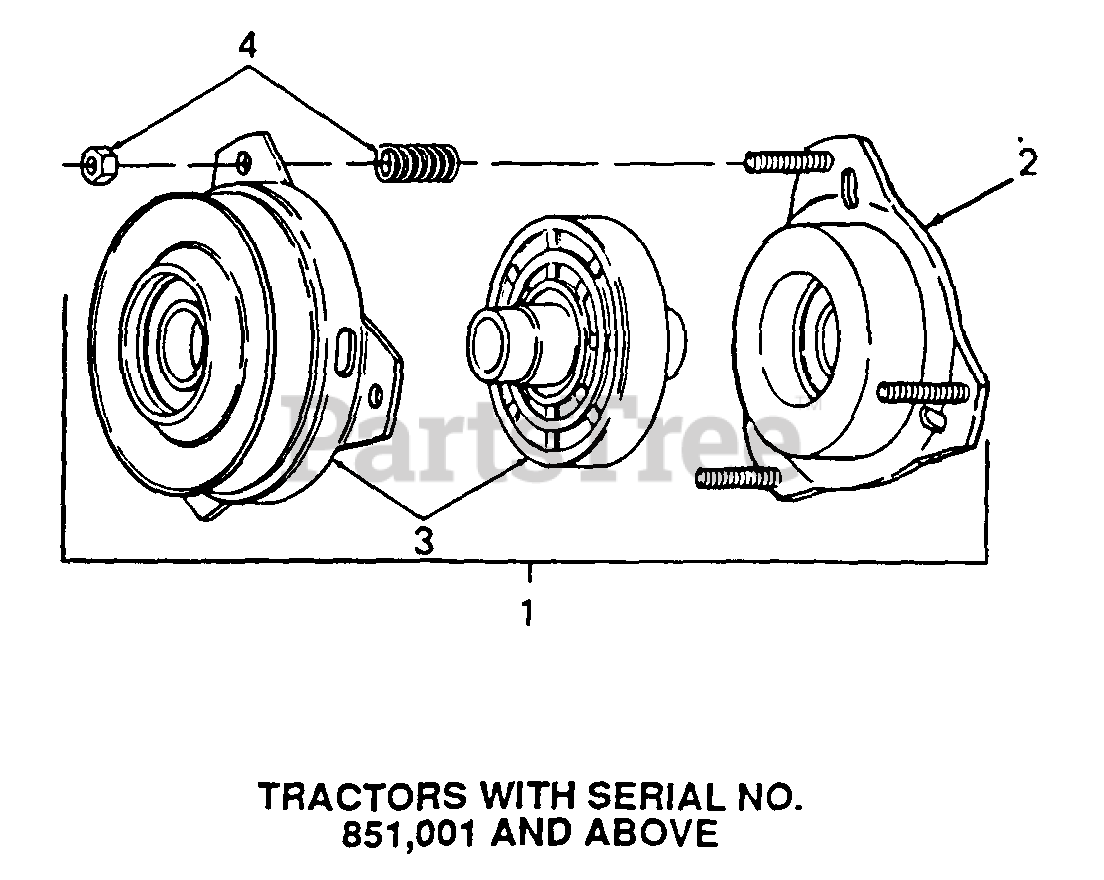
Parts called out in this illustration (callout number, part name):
1	Clutch Assy, PTO
2	Field Assy
3	Kit, Rotor & Armature
4	Mounting Accessories
